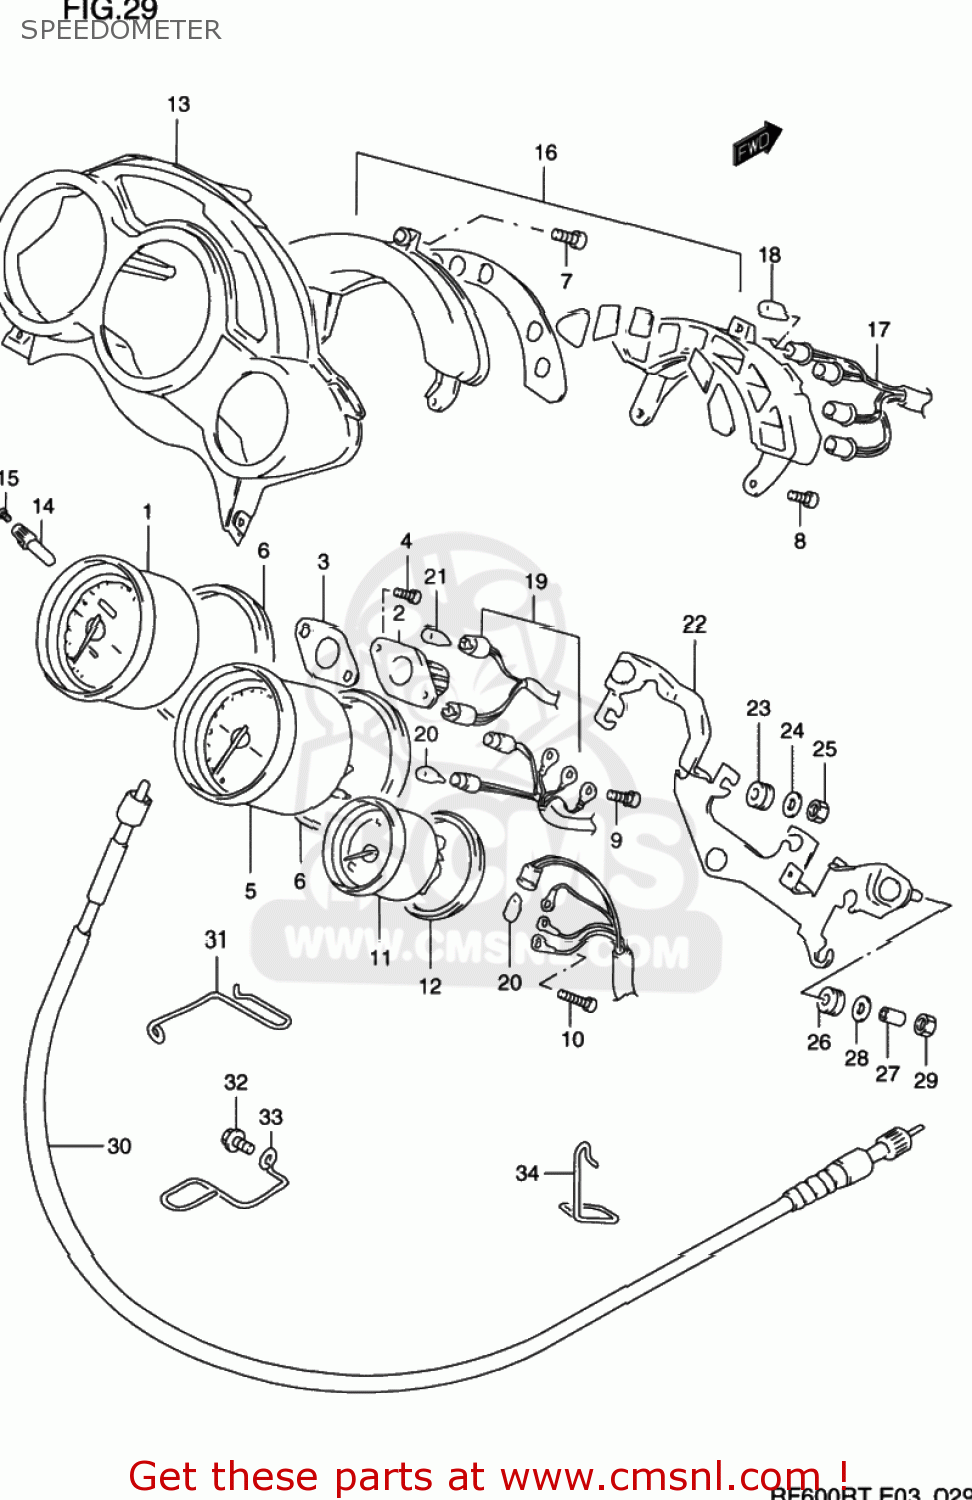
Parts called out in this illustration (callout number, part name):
1	SPEEDOMETER(MILE/KILO)
2	GEAR BOX
3	GASKET,METER GEAR BOX (NAS)
4	SCREW
5	TACHOMETER
6	CUSHION,METER
7	SCREW
8	SCREW
9	SCREW
10	SCREW(3X22)
11	METER,WATER TEMPERATURE
12	CUSHION,TEMP METER
13	VISOR
14	KNOB,TRIP METER
15	SCREW(2X6)
16	BOX ASSY,PILOT
17	CORD ASSY,PILOT BOX
18	BULB(12V3.4W,T10,BF175-01450A)
19	CORD ASSEMBLY
20	BULB(12V1.7W,WB372,T7)
21	BULB(12V1.7W,T6.5)
22	BRACKET,METER
23	CUSHION,METER
24	WASHER,METER
25	NUT
26	CUSHION
27	SPACER (6.1X8X9.5)
28	WASHER
29	NUT
30	CABLE ASSY,SPEEDOMETER
31	GUIDE,SPEEDOMETER CABLE
32	BOLT
33	GUIDE,METER CABLE NO.2
34	GUIDE,SPEEDOMETER CABLE
